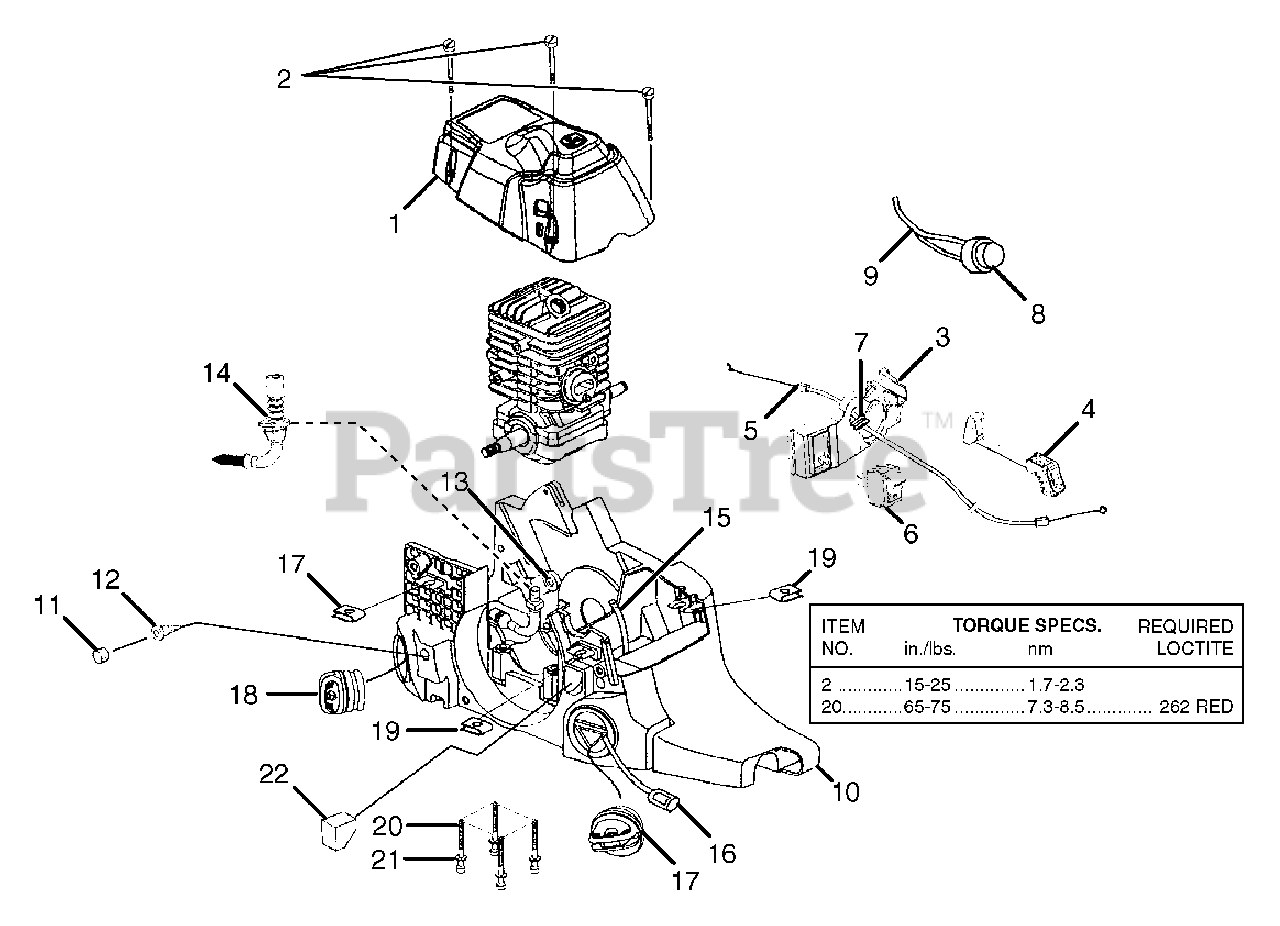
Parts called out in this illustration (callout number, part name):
1	CYLINDER COVER
2	SCREW (10-16 X 1.5 PAN HD.)
3	CONTROL PANEL
4	ROD, CHOKE
5	THROTTLE CABLE
6	SWITCH, ROCKER
7	GROMMET - SPLIT
8	PRIMER BULB
9	RUBBER TUBING (5-1/2 in.)
10	CHASSIS ASSEMBLY (45CC)
11	ELEMENT, FILTER
12	DUCK BILL VALVE
13	OIL OUTLET GROMMET
14	OIL INTAKE TUBE W/FILTER
15	RUBBER TUBING (8-1/2 in.)
16	FUEL FILTER
17	FUEL CAP W/RETAINER
18	OIL CAP W/RETAINER
19	SPEED NUT
20	SCREW (10-24 x 2 in.)
21	WASHER
22	PRE FILTER
